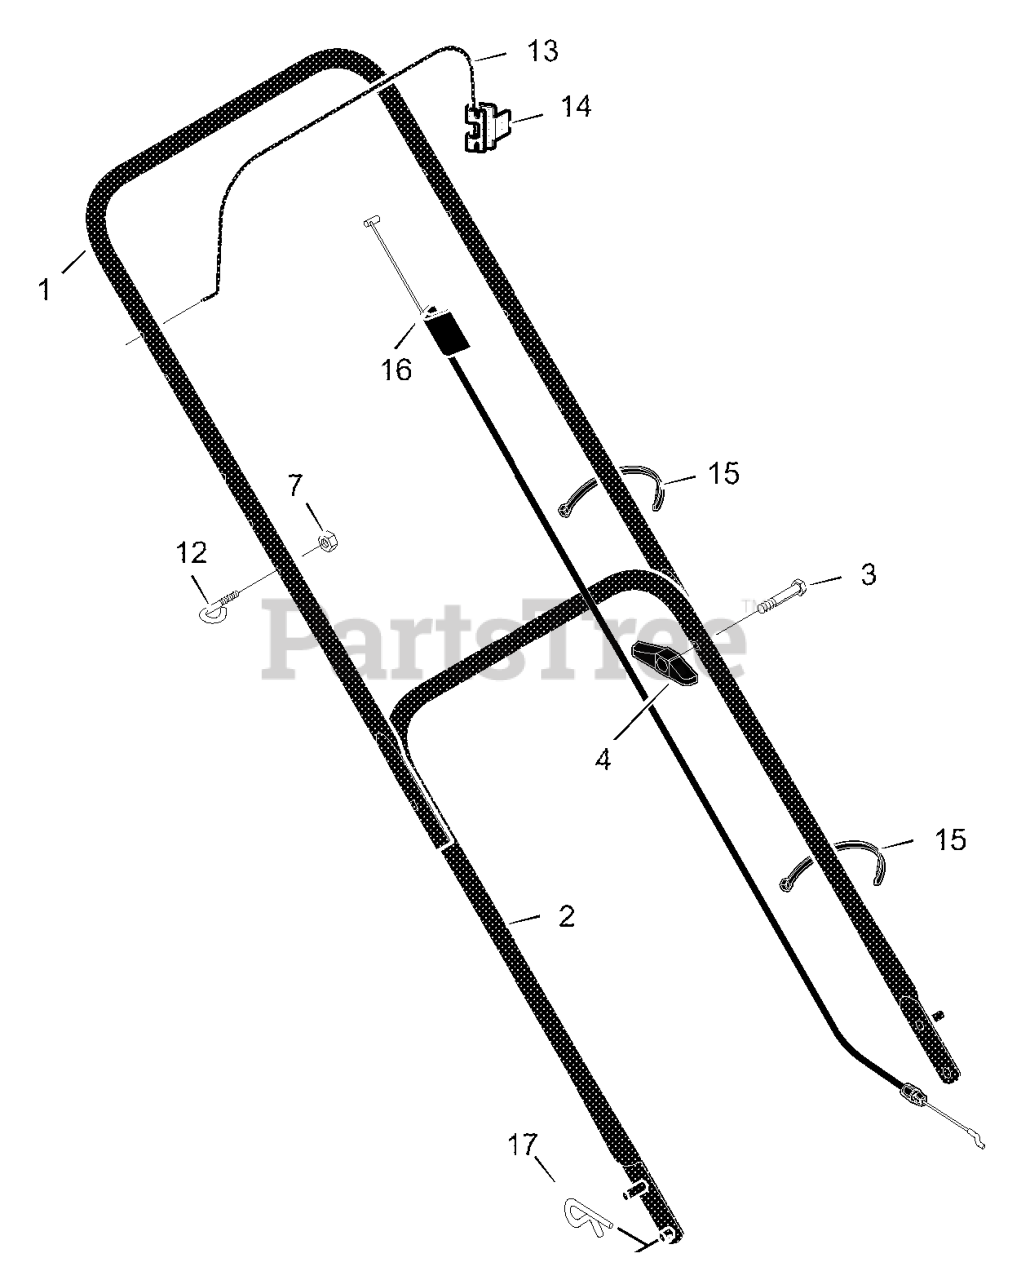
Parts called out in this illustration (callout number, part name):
1	Handle, Upper
2	Handle, Lower
4	Knob, Plastic
7	Locknut
12	Guide, Rope
13	Engine Stop Lever
14	Bracket, Stop Lever
15	Fastener, Cable
16	Engine Stop Cable
17	Pin, Hair
